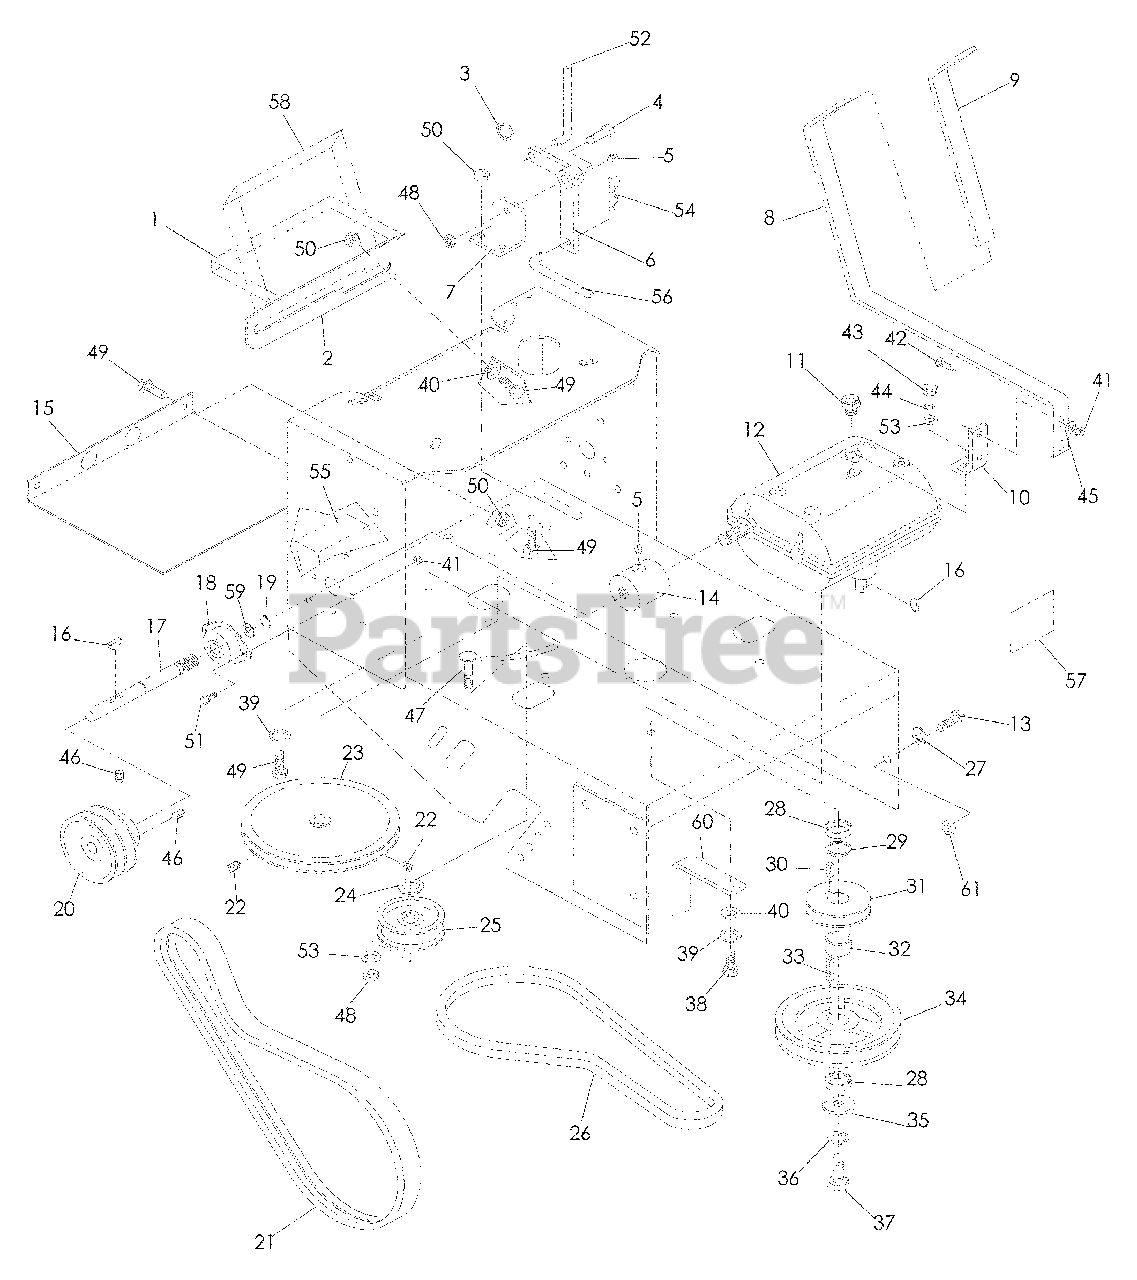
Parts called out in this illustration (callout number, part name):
1	DECAL, SHIFTER
2	PLATE, SHIFTER
4	SB ½-13 x ¾
5	ZERK, ¼-28 STRHT
8	ARM, SHIFTER
9	GRIP, SHIFTER
10	BRACKET, SHIFTER
11	SWITCH, TRANSMISSION
12	TRANSMISSION
13	HCS 7/16-14 x 1½
15	LOWER BELT SHIELD
16	KEY #9 WOODRUFF
17	DRIVE SHAFT
19	RETAINER RING
20	PULLEY, DRIVE (36 & 48)
21	BELT, DRIVE(36 & 48)
22	SETSCREW ¼ NYLOC
23	INPUT PULLEY
25	IDLER PULLEY
26	BELT, TRANSMISSION
27	WASHER 7/16
30	KEY ¼ SQ x ½
33	KEY ¼ SQ x 11/8
34	PULLEY, ENGINE
35	HEAVY WASHER
36	LOCKWASHER 7/16
37	HCS 7/16-20 x 1½
38	HCS M8-1.25 x 30MM
39	LOCKWASHER 5/16 STD
40	WASHER 5/16
41	NUT ¼-20 CENTERLOCK
42	HCS ¼-20 x 1
43	NUT 3/8-24
44	LOCKWASHER 3/8
46	SETSCREW 5/16 NYLOC
47	RHSNB 3/8-16 x 2
48	HLN 3/8-16 CENTERLOCK
49	HCS 5/16-18 x ¾
50	HLN 5/16-18
51	HCS ¼-20 x 5/8
53	WASHER 3/8
54	HAIRPIN, #4
55	DECAL, DANGER
57	DECAL, EXHAUST
58	DECAL, CLUTCH
60	BELT GUIDE, LONG
61	NUT 7/16-14 CENTER LOCK
